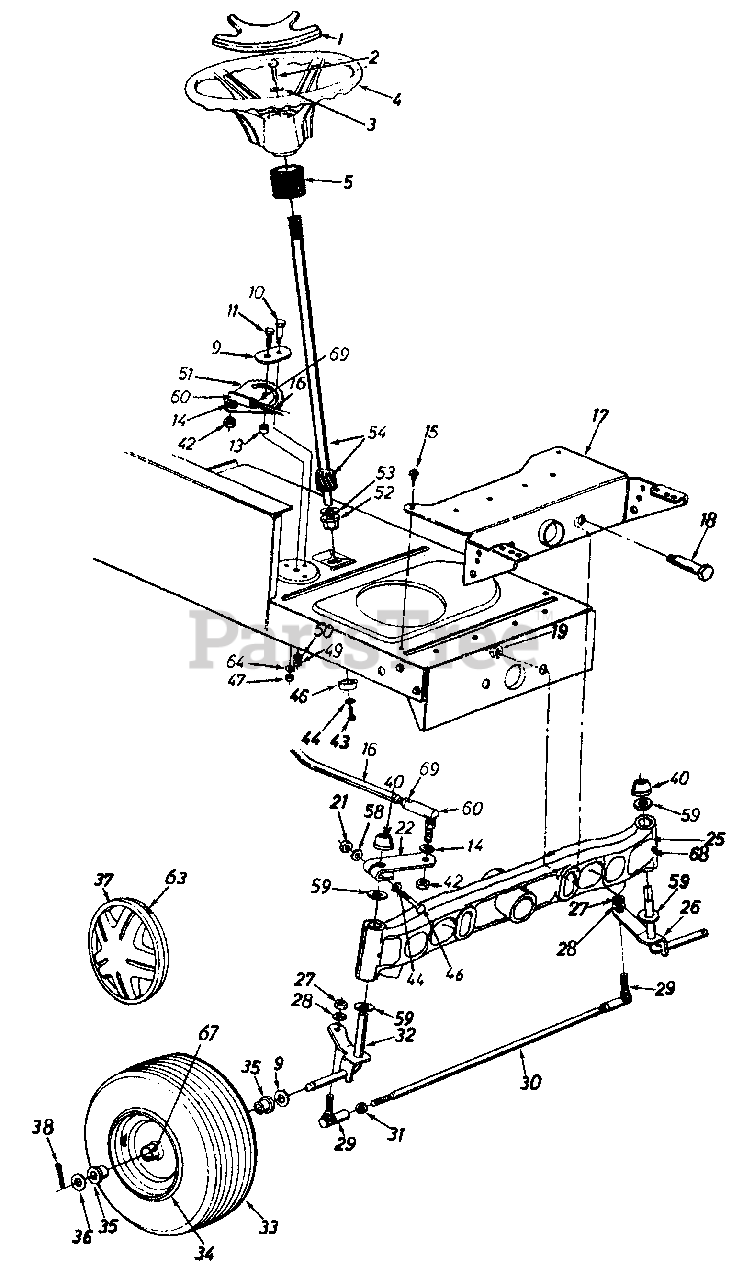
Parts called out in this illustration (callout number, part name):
1	Steering Wheel Cap
2	Hex Bolt 5/16-18 x 1" Lg.
3	Belleville Wash. .345" I.D.
4	Steering Wheel
5	Steering Bellow - 9"
9	Retainer Plate
10	Shoulder Bolt .437" Dia. x .35" Lg. - 5/16-18 Thd.
11	Hex Bolt 3/8-24 x 1.0" Lg. (Grade 5)
13	Spacer .380" I.D. x .625" O.D. x .227
14	L-Wash. 3/8" I.D. (H.D.)
15	Hex Wash. Hd. Self-Tap Scr.
16	Steering Drag Link
18	Shoulder Bolt .498" Dia. x 2.04" Lg.- 3/8-16 Thd.
19	Flanged Hex Nut 3/8-16 Thd.
21	Hex L-Nut 5/16-24 Thd.
22	Steering Arm Front Axle
25	Pivot Bar Ass'y.
26	Front Axle Ass'y.- L.H.
27	Hex Nut 3/8-24 Thd.
28	L-Wash. 3/8" I.D.
29	Ball Joint 3/8-24 Thd.
31	Hex Jam Nut 3/8-24 Thd.
32	Front Axle Ass'y. - R.H.
36	Fl-Wash. .635" I.D. x 1.59" O.D.
37	Hub Cap
38	Cotter Pin 1/8" Dia. x 1.25"
40	Push Cap 5/8" Dia. Rod
42	Hex Jam Nut 3/8-24 Thd.
43	Torx Bolt 5/16-18 x .63" Lg.
44	L-Wash. 5/16" I.D.
46	Cap
47	Hex Cent. L-Nut 3/8-24 Thd.
49	Hex Cent. L-Nut 5/16-18 Thd.
50	L-Wash. 5/16" I.D.
51	Steering Gear Segment
52	Hex . Flg. Brg. 5/8" I.D.
53	Fl-Wash. (Hardened)
54	Steering Shaft
58	Wave-Wash. .32" I.D. x .62" O.D
59	Fl-Wash. (Hardened)
60	Drag Link Ball Joint 7/16-20 Thd.
63	Spring Clip
64	Bell-Wash. .39" I.D. x 1.38" O.D.
67	Grease Fitting
68	Grease Fitting
69	Hex Jam Nut 7/16-20 Thd.
